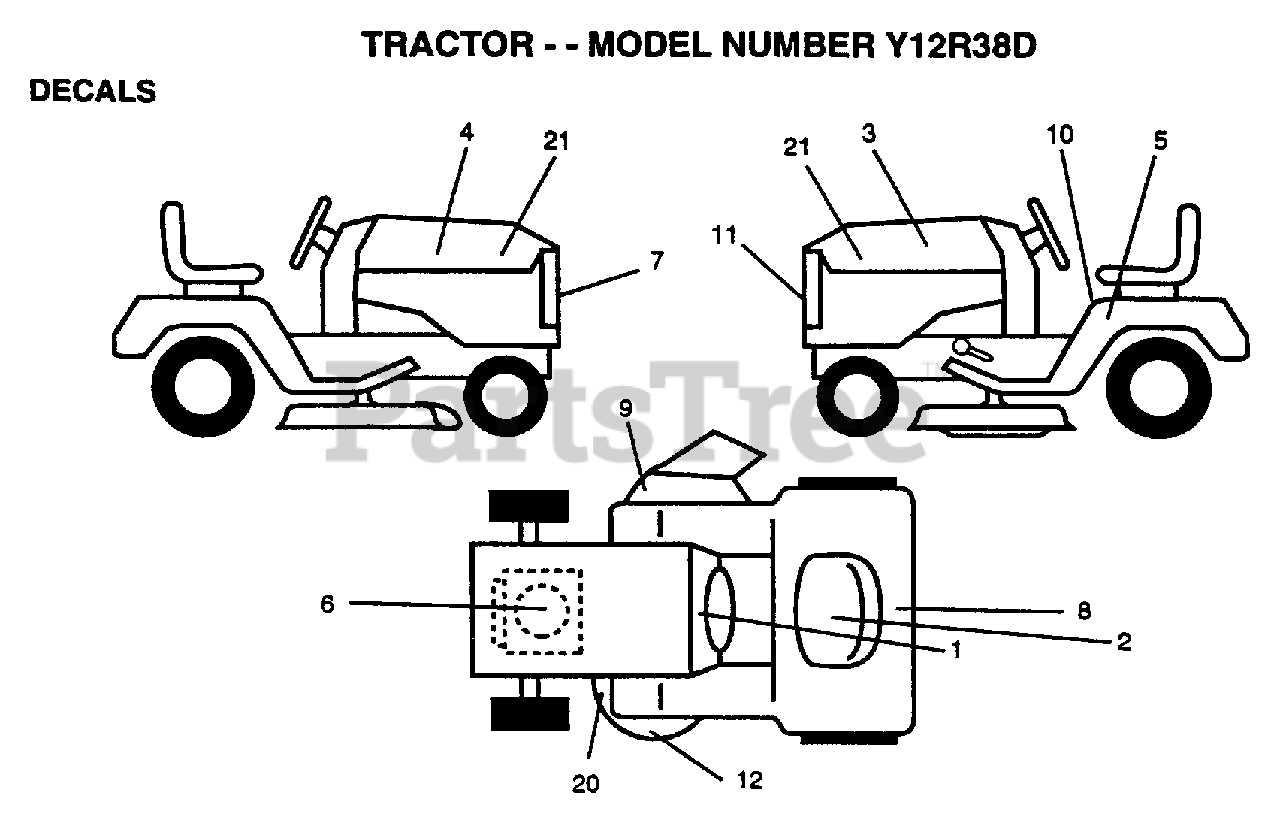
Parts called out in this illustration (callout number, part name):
1	DECAL.INST.OPER.
2	DECAL
5	IND HGT DECK DECA
6	DECAL.ENG.271967
7	DECAL.GRILL.YARDP
9	"DECAL, WARNING"
10	DECAL CAUTION
11	"DECAL,LIGHT BOX"
20	DECAL
21	DECAL.PANEL.SD.12
